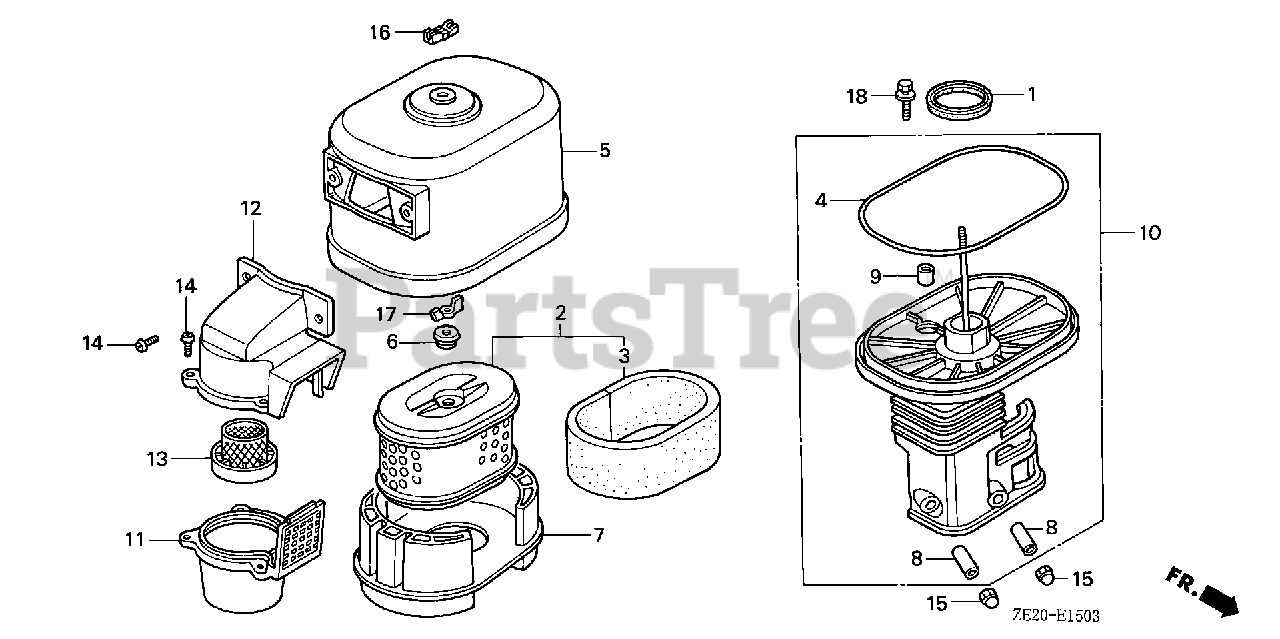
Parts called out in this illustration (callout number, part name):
1	GASKET, ELBOW
2	ELEMENT, AIR CLEANER
3	FILTER (OUTER)
4	SEAL, AIR CLEANER COVER
5	COVER, AIR CLEANER (CYCLONE)
6	GROMMET, AIR CLEANER
8	COLLAR, AIR CLEANER
9	COLLAR B, AIR CLEANER
10	ELBOW, AIR CLEANER
11	CASE, PRE AIR CLEANER
12	CAP, PRE AIR CLEANER
13	GUIDE, PRE AIR CLEANER
14	SCREW, PAN (5X16.5)
15	NUT, CAP (6MM)
16	NUT, AIR CLEANER COVER (DACRO COATING)
17	NUT, TOOL BOX SETTING
18	BOLT-WASHER (6X20)
